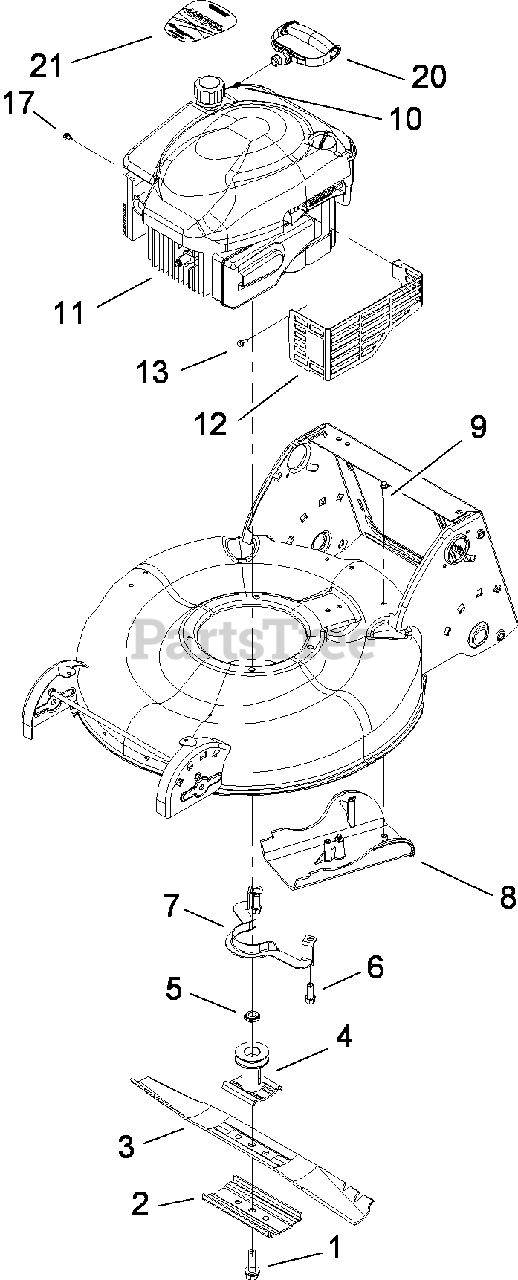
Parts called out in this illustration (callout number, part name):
1	BOLT-BLADE
2	SUPPORT-BLADE
3	BLADE-21 INCH
4	BLADE DRIVER ASM
5	Spacer-Driver
6	SCREW-HWH
8	COVER-BELT
9	SCREW-HWH
10	STOP-ROPE
12	SHIELD-MUFFLER
13	SCREW-TAPTITE
17	SCREW-HWH
20	HANDLE-RECOIL
21	DECAL-ENGINE
